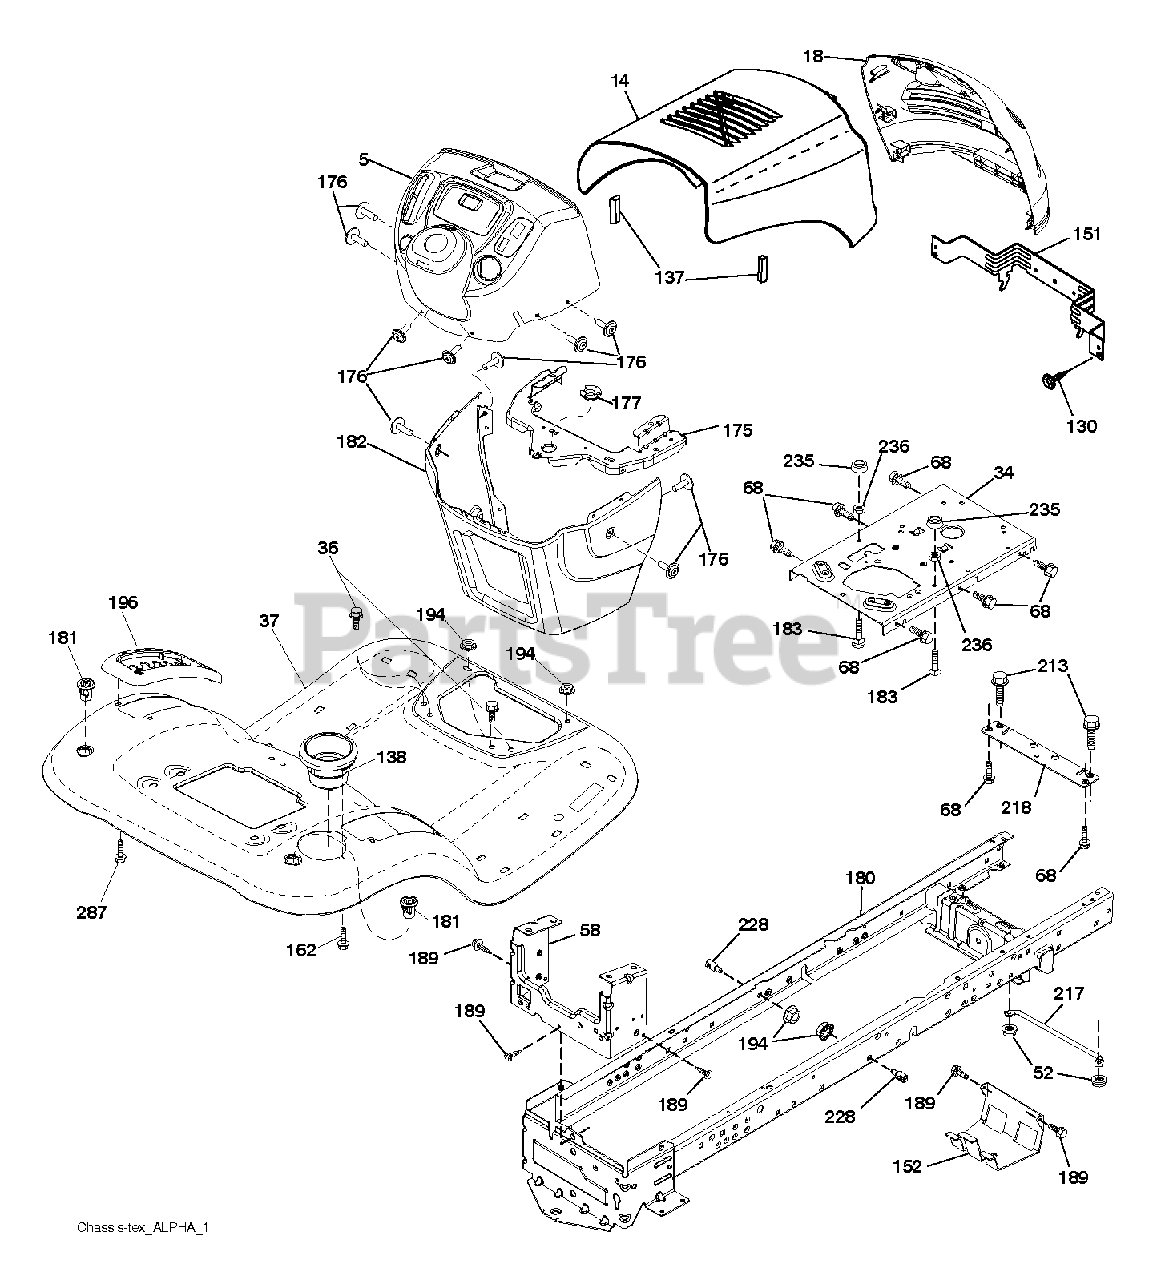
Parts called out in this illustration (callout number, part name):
5	DASH.P/L.TEX.CBL.CL.N/CHK.BLAC
14	HOOD.BLACK.ALPHA
18	GRILL.ALPHA.NO.LIGHTS.POULAN
34	PLATE.ENGINE.WELDED.CHASSIS
36	SCREW 5/16"
37	FENDER.TLT.FS.W/CPH.428
52	LOCKNUT
58	DRAWBAR UPPER 2PC SMALL FENDER
68	SCREW LT
130	SCREW.#10 X 0.750.BOS (2 2)
137	BUMPER.HOOD.LARGE.1.75"
138	CUPHOLDER.TL.TEX.BLACK
151	BRACKET.PIVOT.ALPHA.LT
152	SHIELD.BROWNING.W/TEX
162	SCREW.HI-LO.CONSOLE
175	CROSSMEMBER.LT
176	SCREW.#10-24X5/8.RN.QU
177	BUSHING STEERING
180	CHASSIS.WLDMNT.14GA.2PC.18".TI
181	FEND/FTRST.PCH.CPH.NFW
182	DASH.LOWER.LT.CCS
183	BOLT.5/16-18X1-1/4 FULL THD
189	SCREW
194	NUT LOCK HEX FLANGE 5/16-18
196	CONSOLE.ASM.DECKLFT.BL/RBT.TLT
213	BOLT
217	ROD.PIVOT.HOOD
218	X-PIECE.HOOD.STOP.NON/
228	STUD.FASTNER.W/ANTI-ROTATE
235	SPACER FENDER
236	NUT.CENTERLOCK.5/16-
287	SCREW 1/4X20
